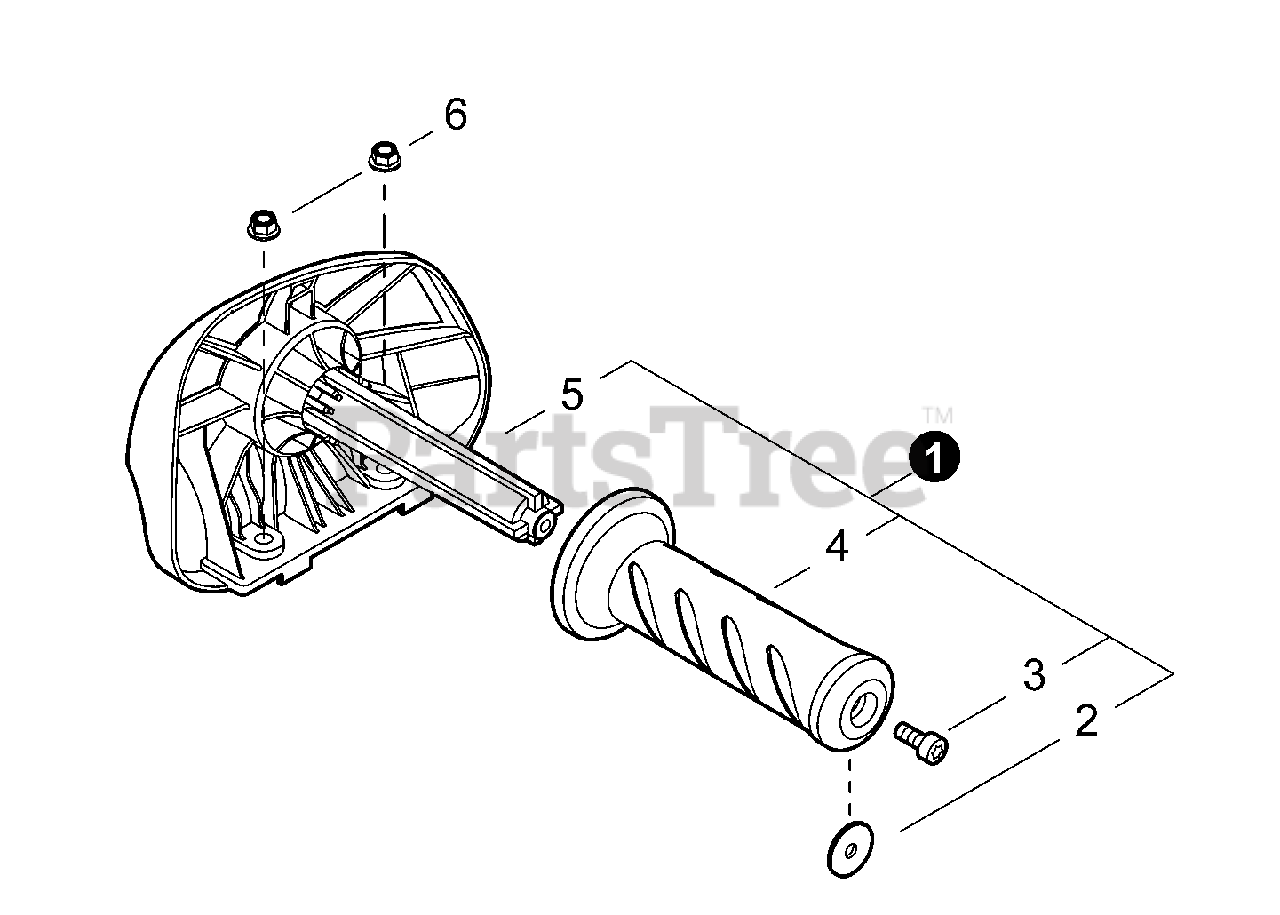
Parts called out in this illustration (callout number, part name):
1	HANDLE ASSY, FRONT
2	WASHER 5MM
3	BOLT, TORX 5×20
5	HANDLE, FRONT
